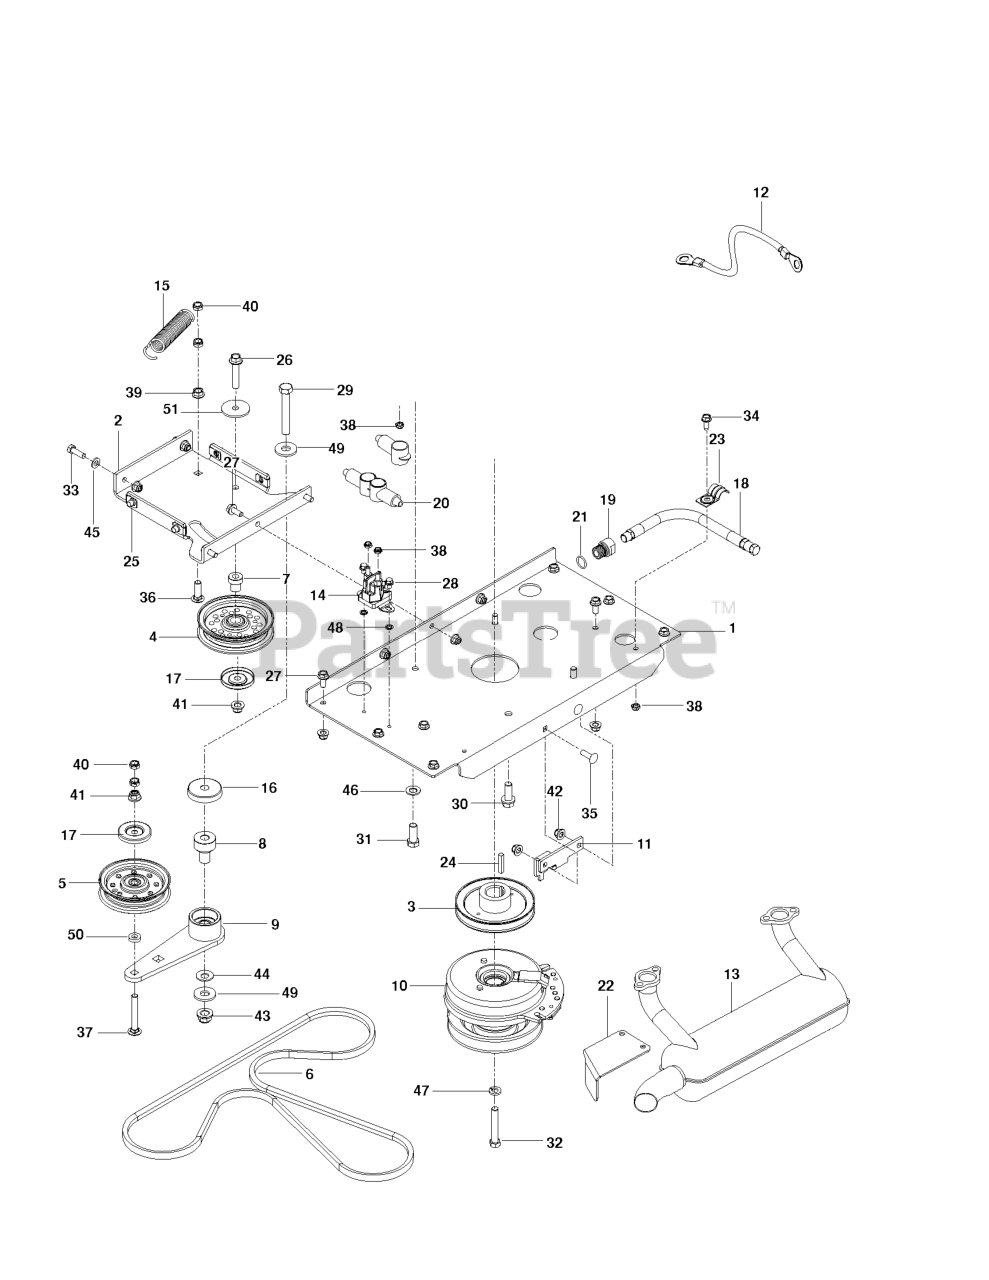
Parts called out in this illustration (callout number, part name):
1	PLATE, ENGINE, BLK
2	PLATE, IDLER, BLK
3	PULLEY, V, 1.125 BORE
4	IDLER PULLEY
5	FLAT IDLER PULLEY
6	BELT, HYDRO, 3400
7	PIVOT, IDLER
8	PIVOT, BEARING
9	ARM, IDLER, STEEL, W/BGS
10	CLUTCH 200 FT LB
11	STOP, CLUTCH, BLACK
12	CABLE POSITIVE
13	MUFFLER.26HP.KAW.FX651V-730V
15	SPRING, PUMP
16	SHIELD, DUST
17	DUST SHIELD
18	HOSE.ASSEMBLY.OIL.DRAIN
19	ADAPTER, OIL DRAIN
22	SHIELD MUFFLER
24	KEY, 1/4 SQ X 1 1/4
25	U-CLIP 5/16-18 NUT RETAINER
26	HHFS 3/8-16 X 2.0 GD 5
27	HHFS 5/16-18 X 3/4
28	HWST 1/4C X 3/8
29	HCS 1/2C X 3 1/4
30	4CS 3/8C X 1 SERRATED HEAD
31	HCS 3/8-16X1.GRD.5.ZD
32	CLUTCH BOLT7/16-20X2.5 GR596HR
33	HCS 5/16C X 1
34	HCS 1/4-20.
35	RHSSNB 5/16C X 1.0
36	RHSNB 3/8-16 X 1-1/4
37	RHSNB 3/8-16 X 2.75
38	JAM NUT 1/4C (2 2 PW01)
39	NUT 3/8C WHIZ
40	NUT HEX 3/8-16 NYLON, THIN
41	NUT 3/8-16 HEX FLG NYLOC ZD
42	5/16-18 NYLOC FLANGE NUT
43	NUT, 1/2-13 HEX FLG NYLOC ZD
44	CONTACT BELLSPR 1/2
45	FLAT WASHER 5/16 SAE
46	WASHER, 3/8 DISC SPRING SPEC
47	WASHER 7/16 LOCK
48	WASHER 1/4 INT TOOTH
49	WASH USS FLAT 1/2
50	WASHER 3/8 X 3/4 X .187 TK
51	WASHER, 3/8 SPEC
